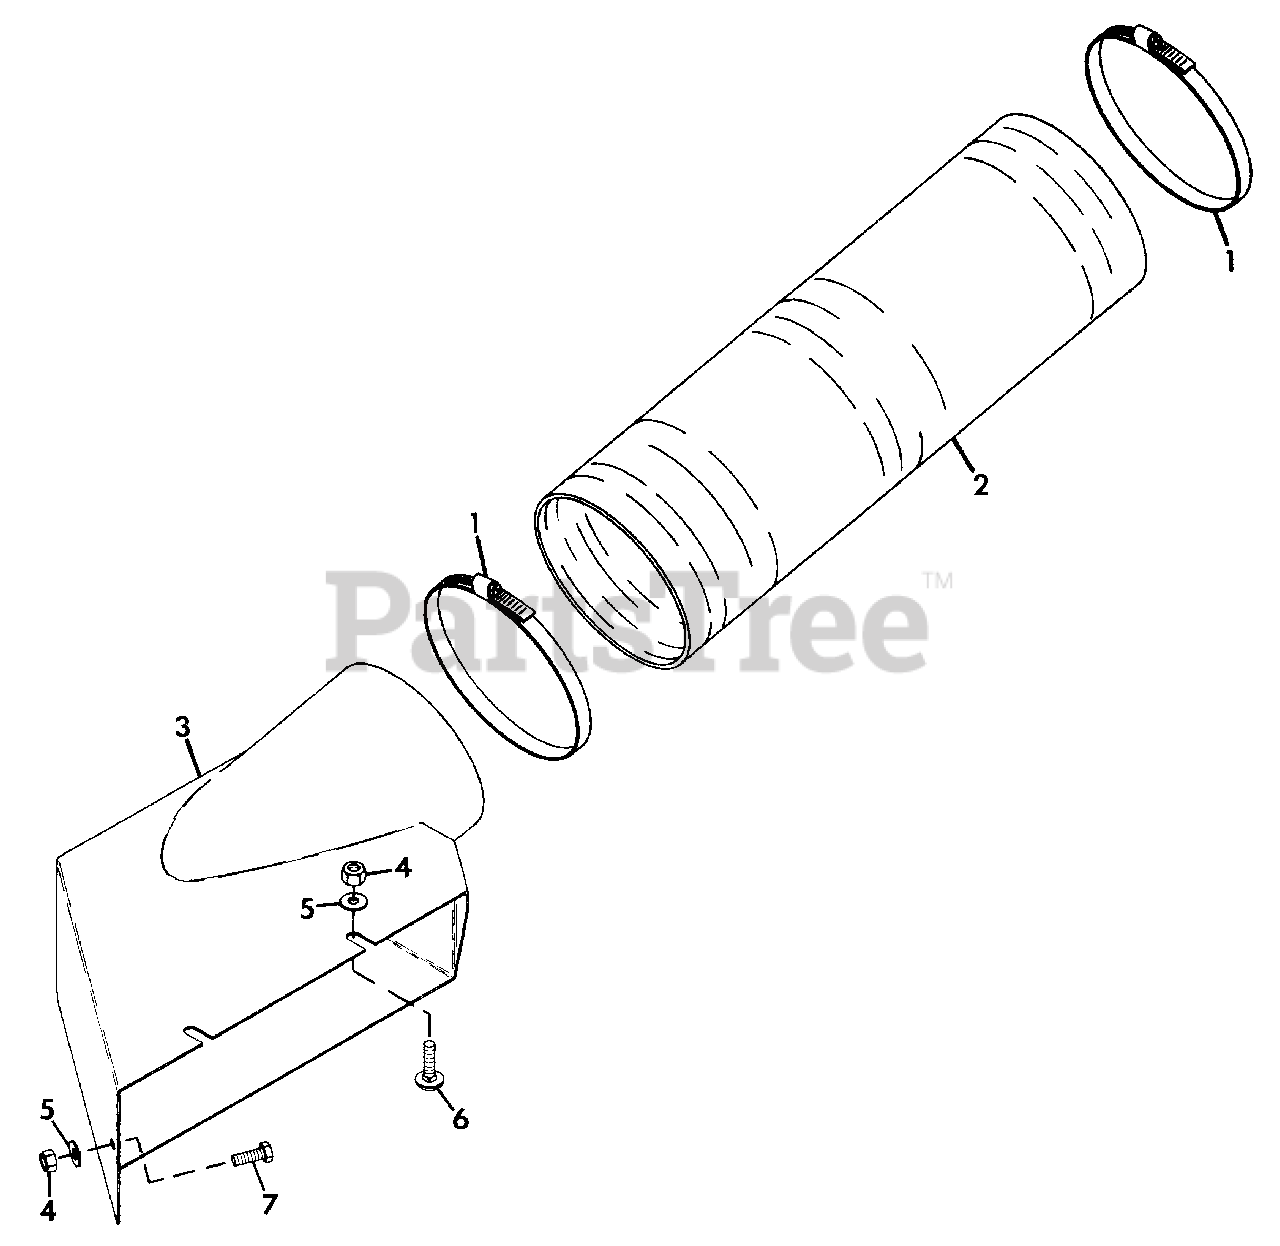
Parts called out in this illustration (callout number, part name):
1	CLAMP
2	HOSE, MOWER TO BLOWER
3	CHUTE, DISCHARGE 50"
4	NUT, LOCK 3/8-16
5	WASHER, FLAT .406X.812X.065
6	BOLT, CARRIAGE 3/8-16X.75
7	BOLT, HEX 3/8-16X1.00
